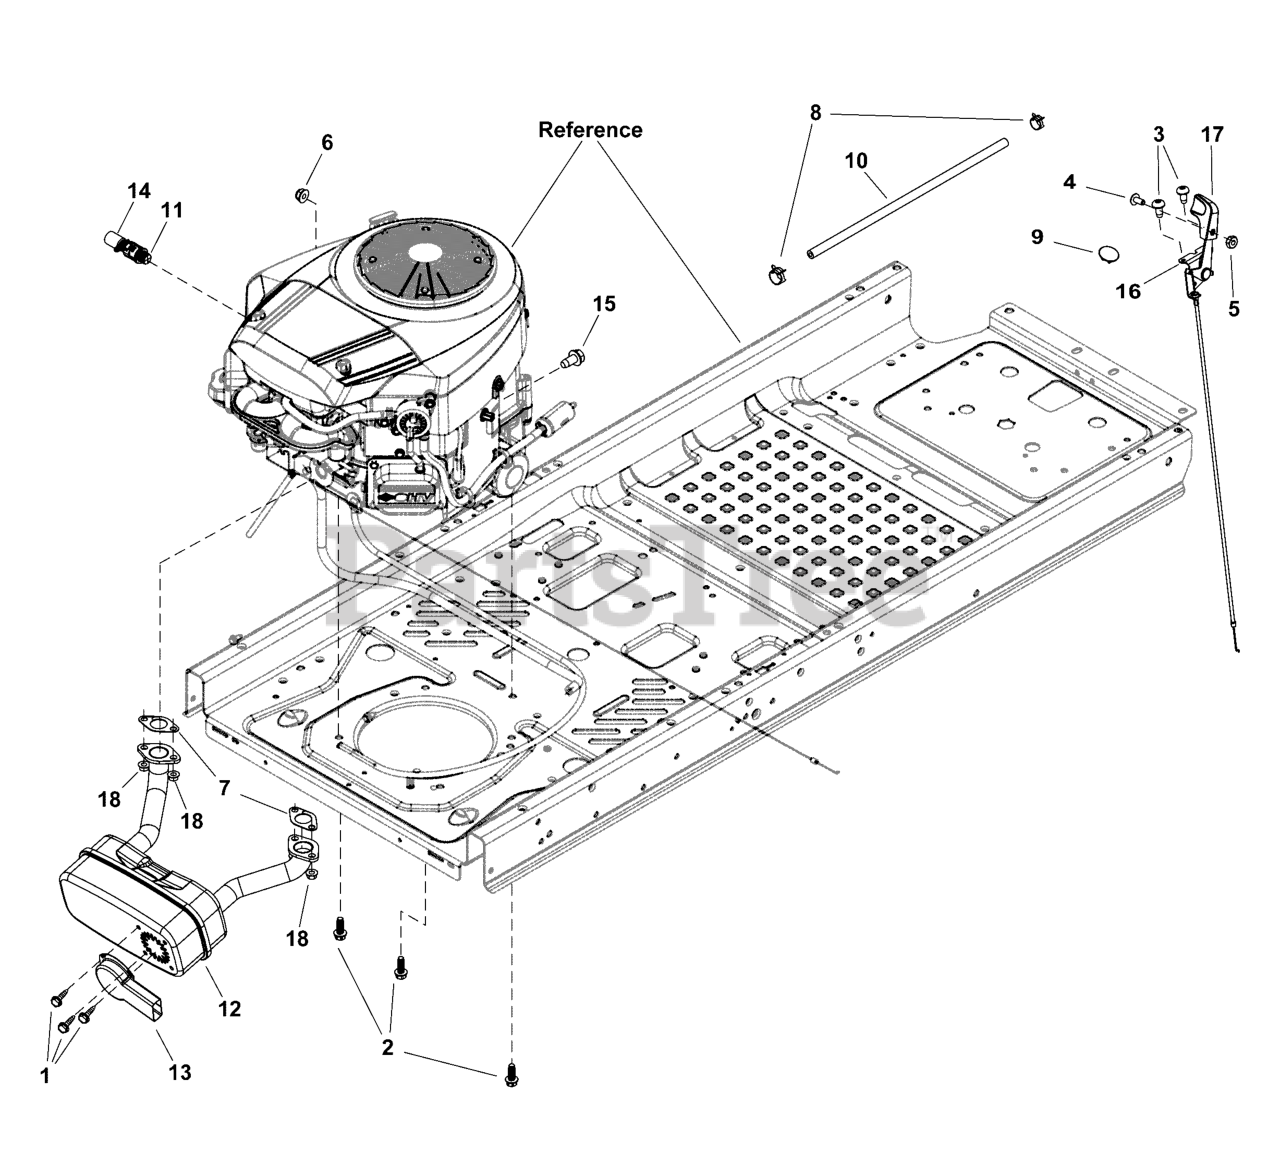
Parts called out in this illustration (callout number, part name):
1	SCREW, #8-18 X .500, Hex Washer
2	CAPSCREW, Hex Head, 3/8-16 x 1, GR5
3	SCREW, 1/4-20 X .50
4	SCREW, #8-32 X .375
5	NUT, #8-32, Hex
6	NUT, Flange Nylock , 1/4-20
7	GASKET, Exhaust
8	CLAMP, .490 DIA., Hose
9	PLUG, Choke
10	HOSE, Fuel
11	DRAIN, Oil
12	MUFFLER, Exhaust (Twin)
13	DEFLECTOR, Muffler, Long
14	HOSE, Oil Drain
15	SCREW, TT, 1/4-20 x 1/2
16	CABLE, Throttle/Choke Control
17	KNOB, Throttle Control
18	NUT, M8, Hex Flange
